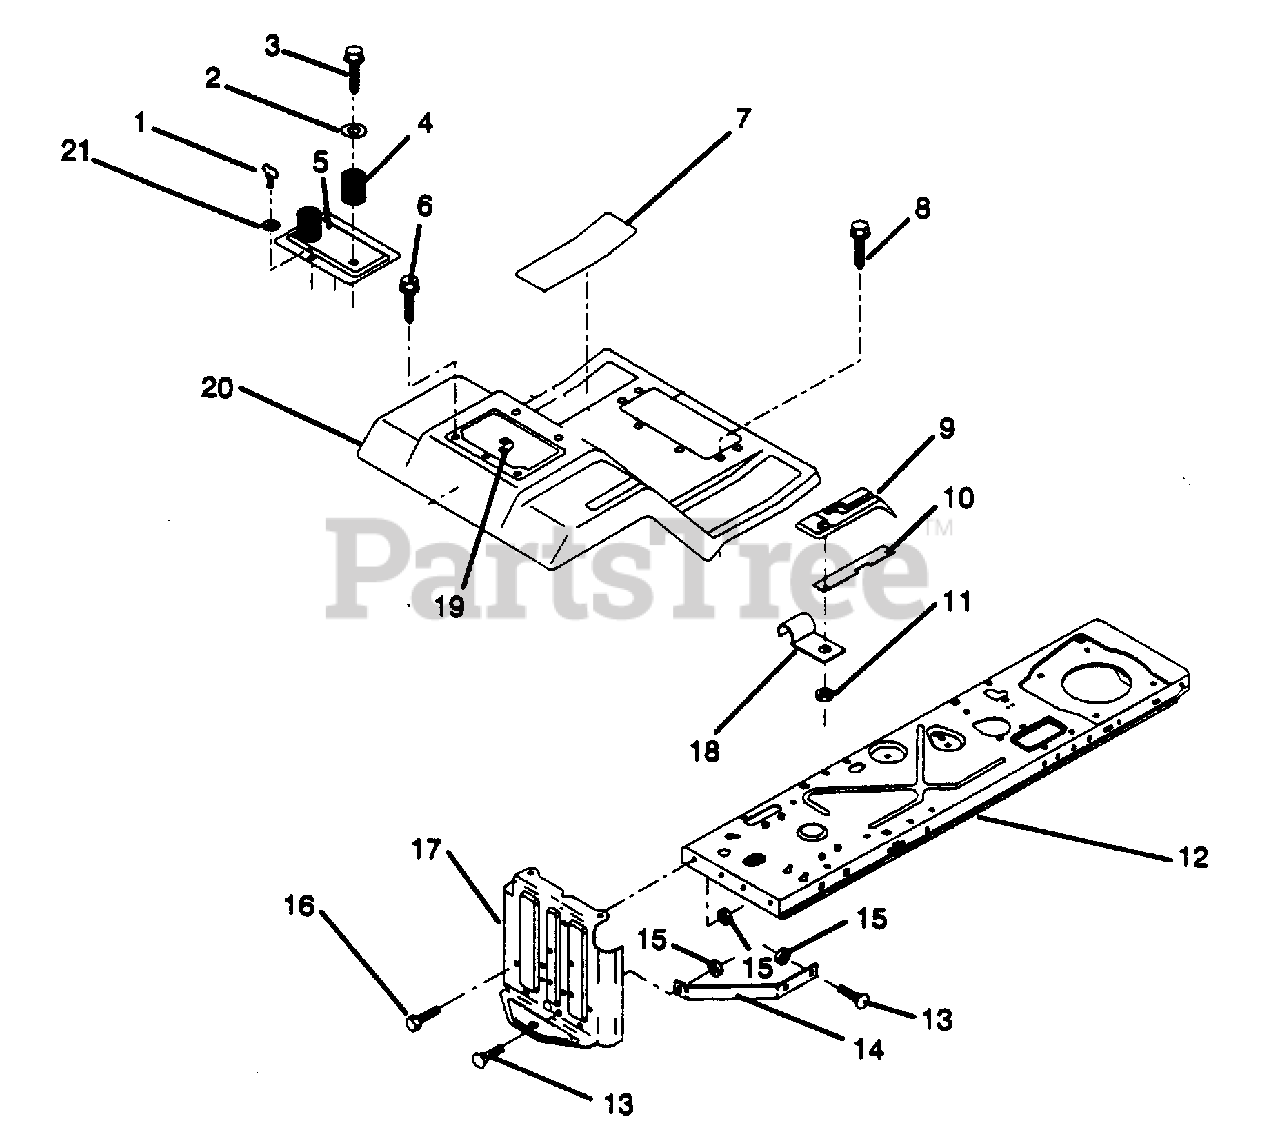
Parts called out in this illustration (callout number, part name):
1	Stud 1/4 Turn
2	Washer 13/32 x 1-1/4 x 12 Ga. (AYP part number)
3	Screw, Hex Wsh. Throdrol. 3/8-16 x 3/4 (AYP part number)
4	Spring, Compression, Seat (AYP part number)
5	Door, Fender (AYP part number)
6	Screw, Hex Wsh. Thrdrol. 5/16-18 x 1/2 (AYP part number)
7	Pad, Footrest (AYP part number)
8	Screw, Hex Wsh. Thrdrol. 5/16-18 x 3/4
9	Console, Shift Control (AYP part number)
10	Bar, Shift Lock (AYP part number)
11	Nut, Self-Thd Wsh-Hd 3/16 (AYP part number)
12	Assembly, Frame (AYP part number)
13	Bolt, Carriage 5/16-18 UNC x 3/4
14	Brace, Drawbar (AYP part number)
15	Nut, Crownlock 5/16-18
16	Bolt, Hex Hd. 5/16-18 UNC x 3/4 (AYP part number)
17	Drawbar (AYP part number)
18	Clip, Insulated (AYP part number)
19	Receptacle, 1/4 Turn (AYP part number)
20	Fender/Footrest (AYP part number)
21	Retainer, 1/4 Turn (AYP part number)
